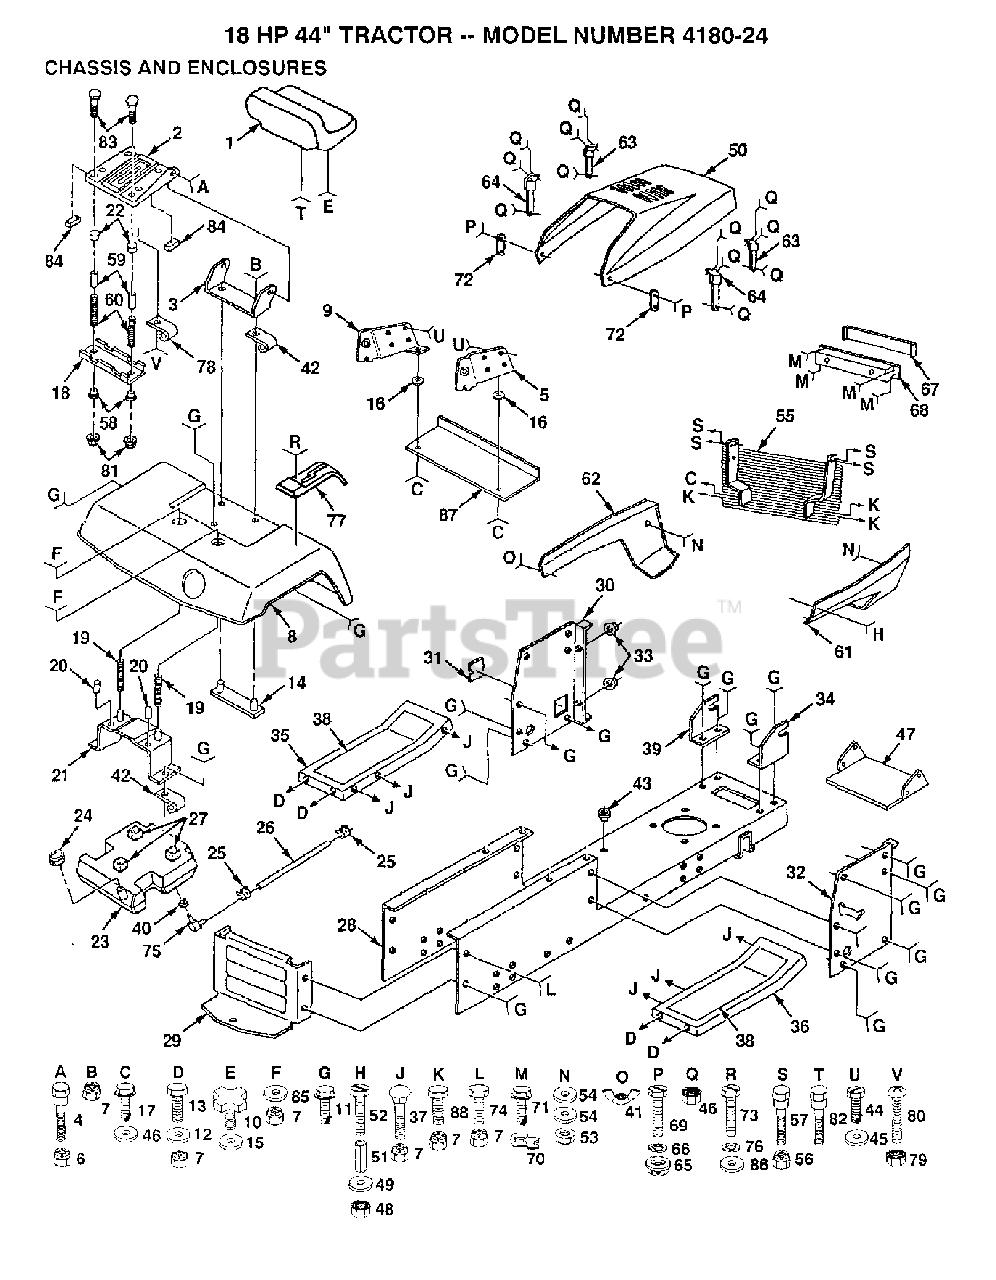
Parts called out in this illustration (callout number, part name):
2	SEAT, CUSHION
3	BRKT,SEAT PIVOT**
4	BOLT, SHOULDER LT
5	BRACKET NLA
6	LOCKNUT
7	LOCKNUT
8	Poulan TBD
9	SUPPORT LH YTH
12	WASHER
14	STRAP-FENDER YT
16	WASHER
18	BRKT SWITCH
19	SPRING COMPRESSION
20	NUT-PUSH YT
22	CAP SPRING
23	FUEL TANK LT
25	HOSE CLAMP
26	FUEL LINE
27	PAD-SPACER LT
29	DRAW BAR
30	PANEL DASH LH NLA
31	COVER ACCESS
32	PANEL LT NLA
33	SNAP BUSHING T
34	SUPPORT RH YTH
35	FOOTREST LH**
36	FOOTREST RH
38	FOOTREST PAD
39	SUPPORT LH YTH
40	BUSHING OUTLET T
41	WING NUT
42	CLIP T
44	Screw, Lt
45	WASHER
46	WASHER
48	NUT **
49	WASHER
50	Poulan TBD
51	SPACER LT
52	SCREW
53	NUT
54	WASHER PM
56	NUT.CROWNLOCK.1/4
57	Bolt
59	SPACER SPLIT
60	SPRING COMPRESSED
61	Poulan TBD
62	Poulan TBD
65	NUT.WELD
66	LOCKWASHER
69	SCREW
72	LATCH.HOOD.
75	FUEL TANK STEM GT
76	Lock Washer
77	CONSOLE SHIFTER
78	CLIP T
79	NUT,KEPS
80	SCREW **
81	NUT T
82	BOLT, SHOULDER**
83	BOLT CARRIAGE 1/4-20X1 3/8
84	STRIP FORM
87	Poulan TBD
88	BOLT
89	NUT
